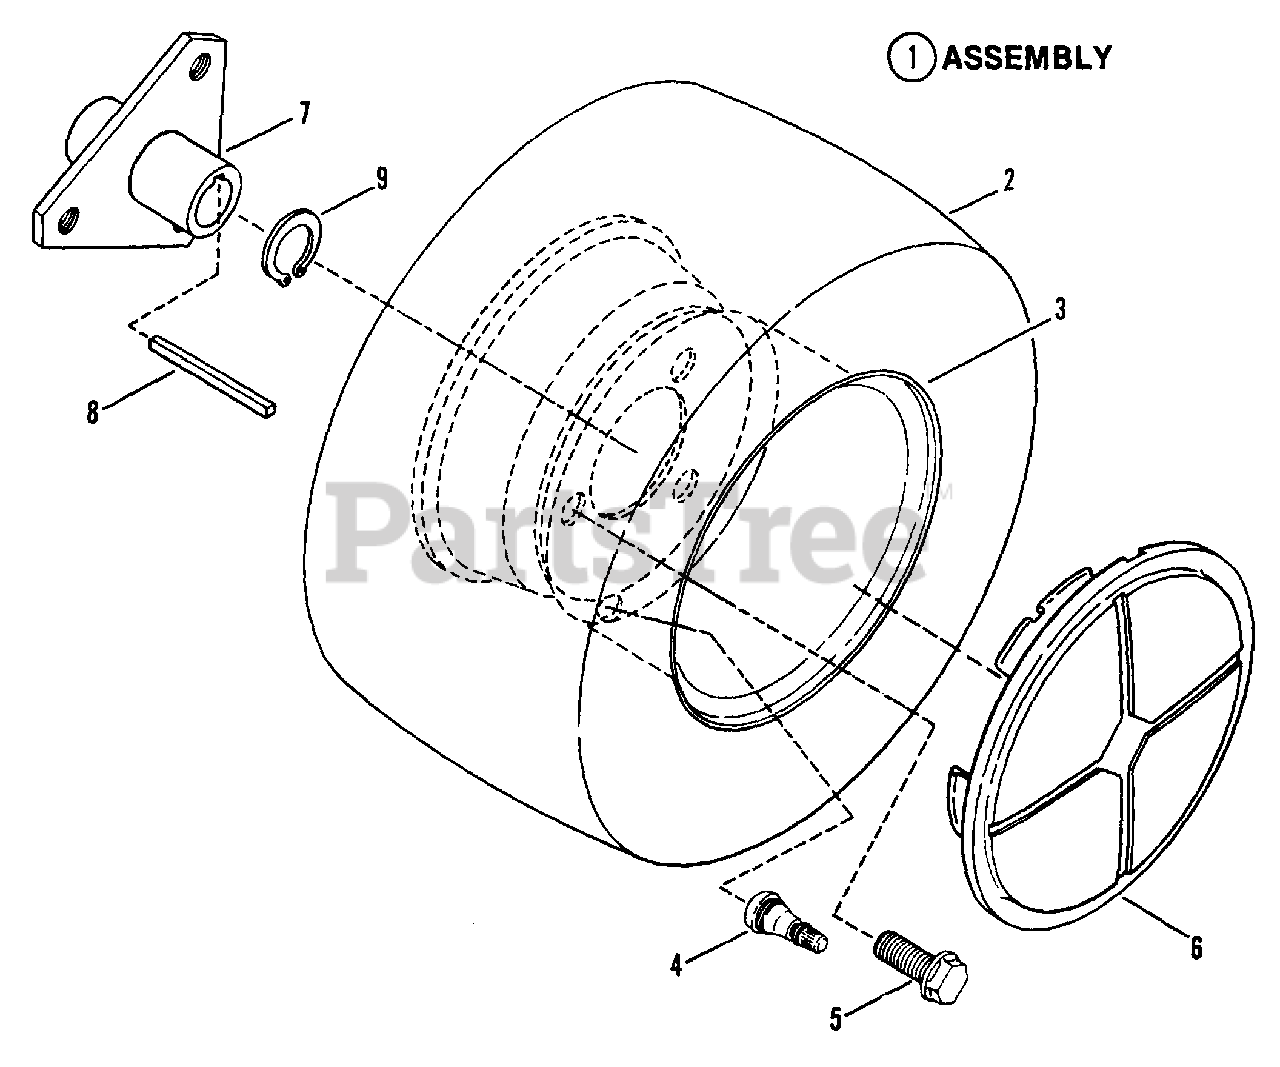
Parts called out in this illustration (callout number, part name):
1	ASSEMBLY, Rear Tire & Rim (No longer available)
2	TIRE, 18-8.50 x 8
2	TIRE, 18-7.50 x 8
3	RIM, 8 x 7
3	RIM, 8 x 5.375
4	VALVE, Air (Snap-in)
5	BOLT, 1/2-20 x 3/4" Lug
6	WHEEL-COVER
7	HUB, Rear Wheel
8	KEY, Square, 3/16 x 2 1/2"
9	RING, Retaining EXT .75
